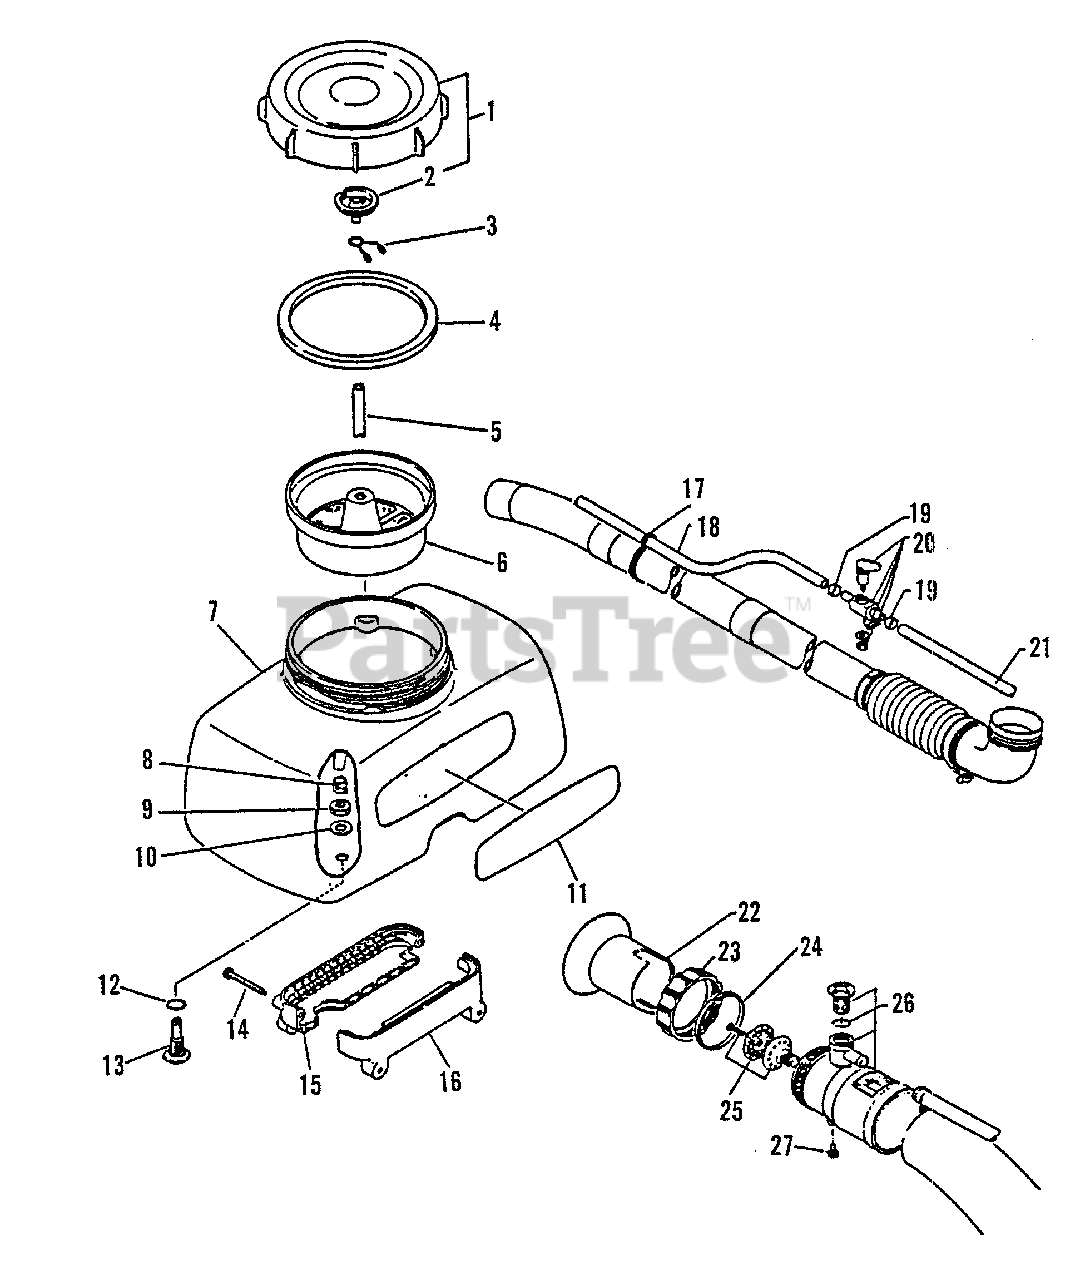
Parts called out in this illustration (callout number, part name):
1	CAP, CHEMICAL TANK
2	VENT, TANK
3	CLAMP
4	GASKET, CAP
5	HOSE, FLUID
6	FILTER, CHEMICAL TANK
7	TANK, CHEMICAL
8	CLAMP
9	NUT - 12
10	WASHER - 12
11	LABEL - ECHO
12	O-RING - 16
13	CONNECTOR, PIPE
14	SCREW - 5X55
15	HOLDER, TANK
16	HOLDER, TANK
17	CLIP
19	CLIP - 13
20	VALVE ASSY
21	HOSE
21	NOZZLE ASSY
26	CONTROL, VOLUME
27	SCREW - 5X12
